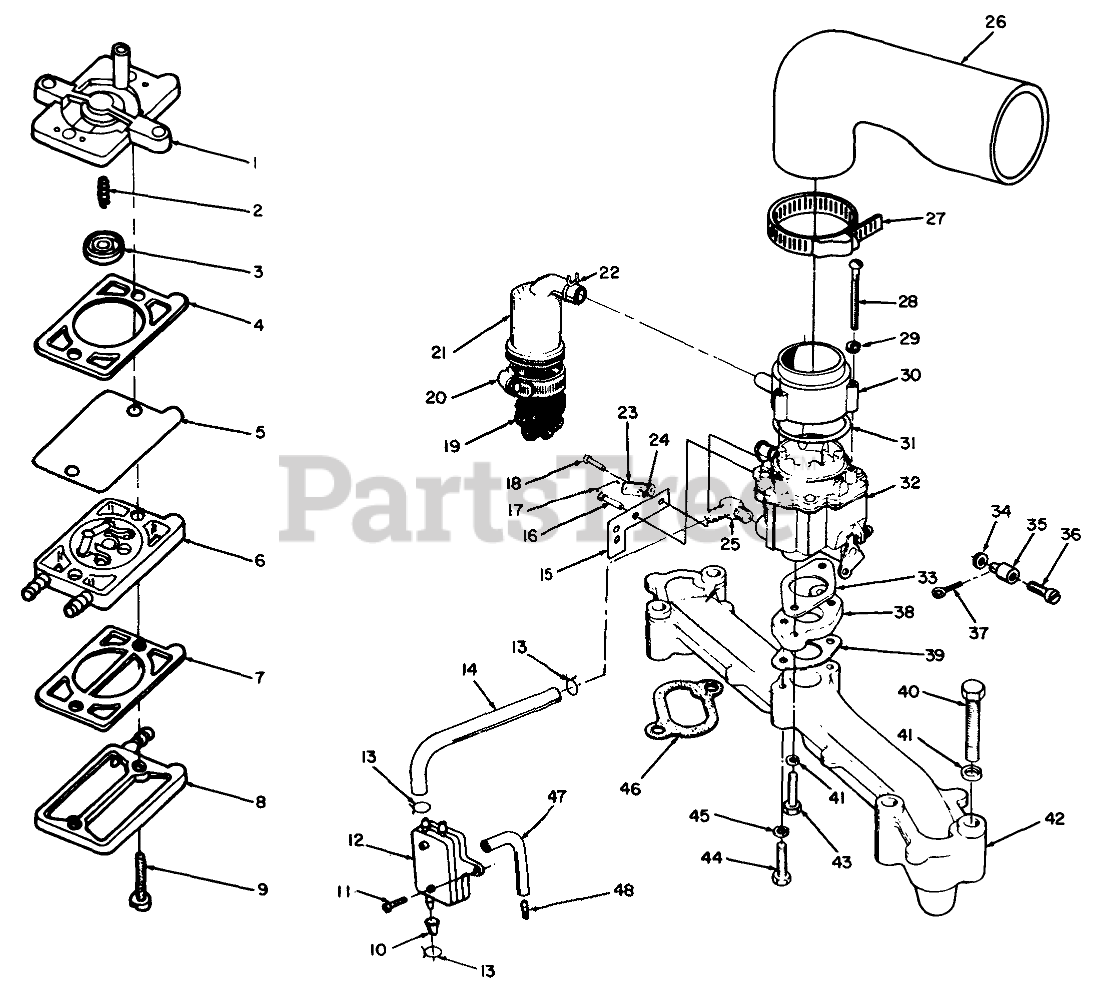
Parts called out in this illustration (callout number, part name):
1	Base, Pump
2	Spring, Fuel Pump
3	Plate, Drive-Fuel Pump
4	PUMP COVER GASKET
5	Diaphragm-Fuel Pump
6	Valve Assembly, Reed-Fuel Pump (Includes Cap & Clamp)
7	Gasket-Cover to Valve Assy.
8	Cover-Pump
9	PUMP SCREW
10	CAP-FUEL OUTLET
11	SCREW-TAPPING PAN HD
12	Pump, Fuel-Vacuum Pluse (Incl. Ref. #1-9)
13	CLAMP
14	Hose
15	BRACKET
16	HS WSHR HD CAPSCREW
17	LINK-CHOKE
18	BOLT-SHOULDER
19	FILTER
20	CLAMP
22	CLAMP
23	SWIVEL-CHOKE
24	WASHER-LOCK, INT
25	HOSE ELBOW
26	INLET ASM
27	HOSE CLAMP
28	RD HD MACH SCREW
29	WASHER-LOCK
30	ADAPTER
32	Carburetor, Complete (Incl. Ref. #33)
33	Gasket
34	Washer
35	SWIVEL
36	Screw
37	PIN-COTTER
38	Adapter, Carburetor
39	CARB GASKET
40	SCREW-HH
41	WASHER-LOCK
42	Manifold, Intake
43	SCREW-HH
44	SCREW-HH
45	WASHER-LOCK
46	Hose-Oil
47	Line-Pulse
48	TUBE-PORT, VACUUM
